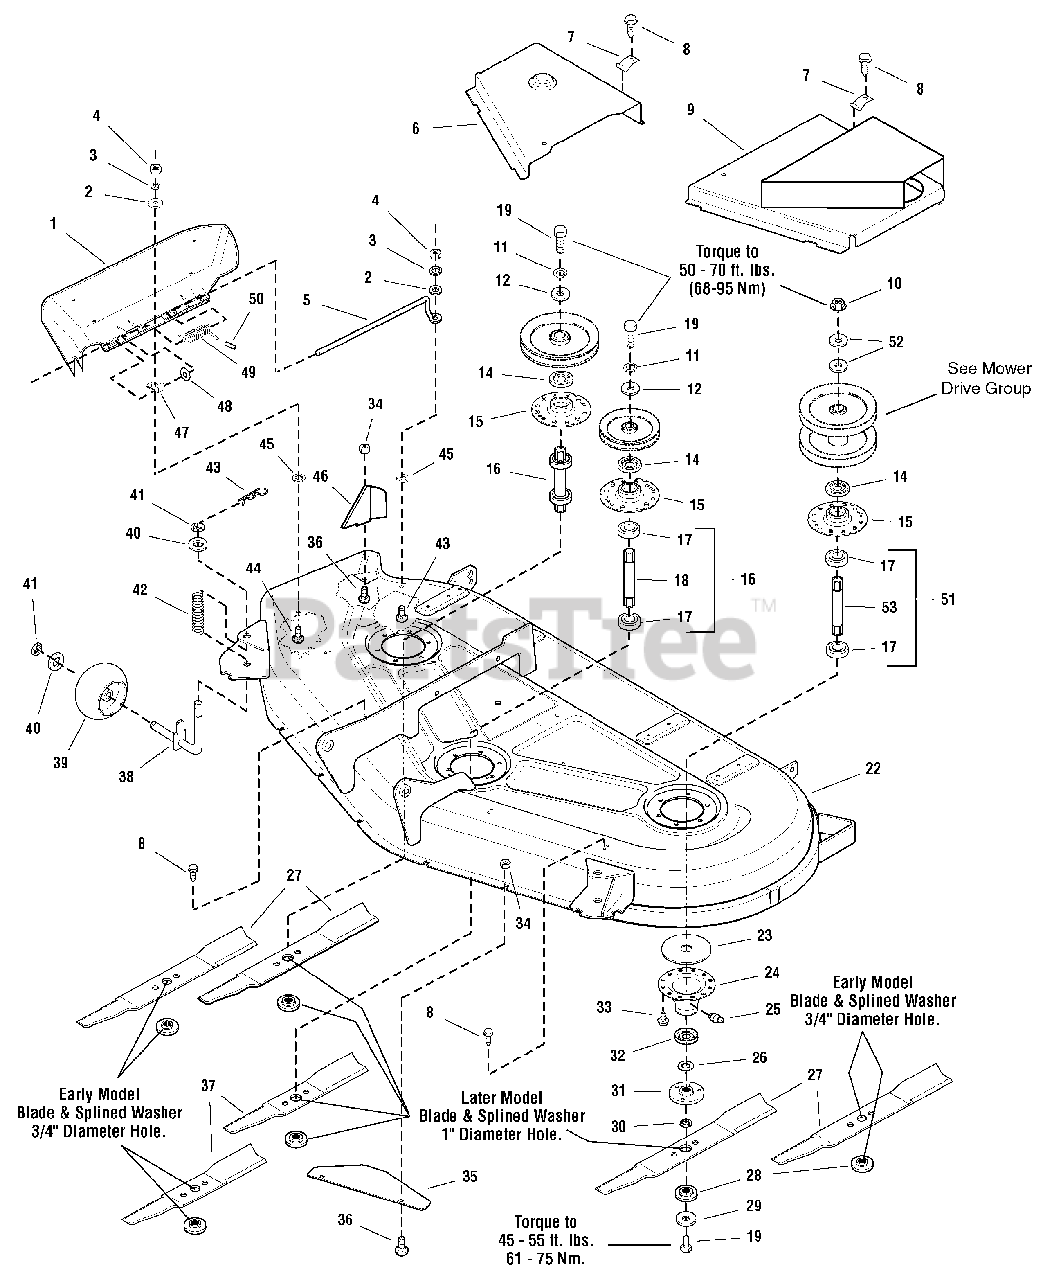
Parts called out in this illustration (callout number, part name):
1	DEFLECTOR, Plastic
2	WASHER, Plain, 1/4
3	WASHER, Lock, 1/4
4	NUT, 1/4-20
5	ROD, Deflector, Front
6	COVER, Arbor, RH (Orange)
6	COVER, Arbor, RH (Red)
7	CLIP, Spring
8	CAPSCREW, Hex Washer Head Taptite, 1/4-20 x 3/8
9	ASSEMBLY, Cover, Arbor, LH (Orange)
9	ASSEMBLY, Cover, Arbor, LH (Red)
10	NUT, Hex Flange, 9/16-18
11	WASHER, Lock, 7/16
12	WASHER, 7/16
13	PULLEYS & HUB ASSEMBLY, Double, LH
14	SHIELD, Bearing Upper, Arbor
15	HOUSING, Arbor, Top
16	ARBOR SHAFT & BEARING ASSEMBLY (Includes Ref. Nos. 17 & 18)
17	BEARING, Ball, 3/4 x 1-3/4 x 5/8
18	ARBOR SHAFT
19	CAPSCREW, Hex Head, 7/16-14 x 1-1/4, G8
20	PULLEY & HUB ASSEMBLY, Center
21	PULLEY & HUB ASSEMBLY, RH
22	HOUSING ASSEMBLY, Mower Housing, 54" (Orange)
22	HOUSING ASSEMBLY, Mower Housing, 54" (Red)
23	GASKET, Foam
24	ASSEMBLY, Housing, Bottom (Includes Ref. No. 25)
25	FITTING, Lube
26	WASHER, Shim
27	BLADE, Mower, 20-1/2 (3/4" Diameter Center Hole in Blade)
27	BLADE, Mower, 20-1/2 (1" Diameter Center Hole in Blade)
28	WASHER, Splined (3/4" Diameter Center Hole in Blade)
28	WASHER, Splined (1" Diameter Center Hole in Blade)
29	WASHER, Spring
30	RING, Self Locking
31	ADAPTER, Blade
32	SHIELD, Grass
33	CAPSCREW, Hex Washer Head Taptite, 5/16-18 x 3/4
34	NUT, Hex, Nylon Lock, 5/16-18
35	BAFFLE, Front, Anti-Blowout
36	CARRIAGE BOLT, 5/16-18 x 3/4, (1 Needed for Rear Baffle)
37	BLADE, Mower, 16 (3/4" Diameter Center Hole in Blade)
37	BLADE, Mower, 16 (1" Diameter Center Hole in Blade)
38	SPINDLE & STOP ASSEMBLY
39	WHEEL, Gauge
40	WASHER, Plain, 5/8
42	SPRING, Compression
43	CLIP, Hairpin
44	CARRIAGE BOLT, 1/4-20 x 7/8
45	NUT, Push
46	BAFFLE, Discharge
47	CLAMP, Wire
48	WASHER, Plain, 5/16
50	CAP, Spring End
51	SHAFT & BEARING ASSEMBLY
52	WASHER, Belleville
53	ARBOR SHAFT
